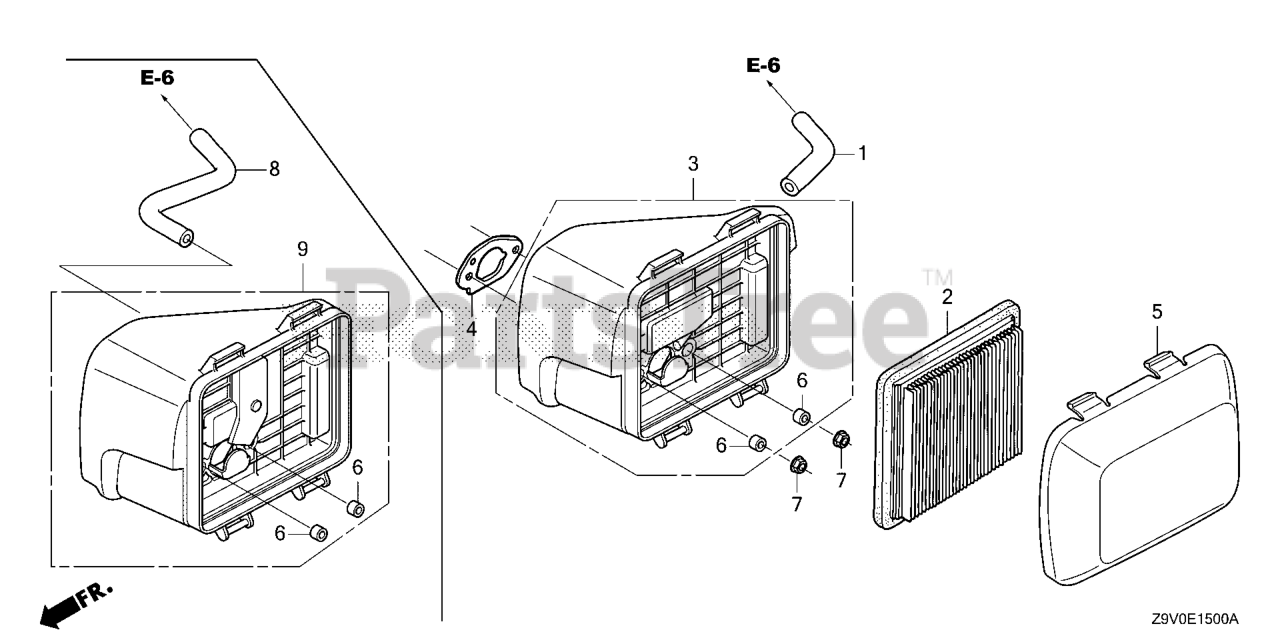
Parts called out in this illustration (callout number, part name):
1	TUBE, BREATHER
2	ELEMENT, AIR CLEANER (WIX FILTERS)
3	HOUSING, AIR CLEANER
4	GASKET, AIR CLEANER
5	COVER, AIR CLEANER
6	COLLAR, AIR CLEANER
7	NUT, FLANGE (6MM)
